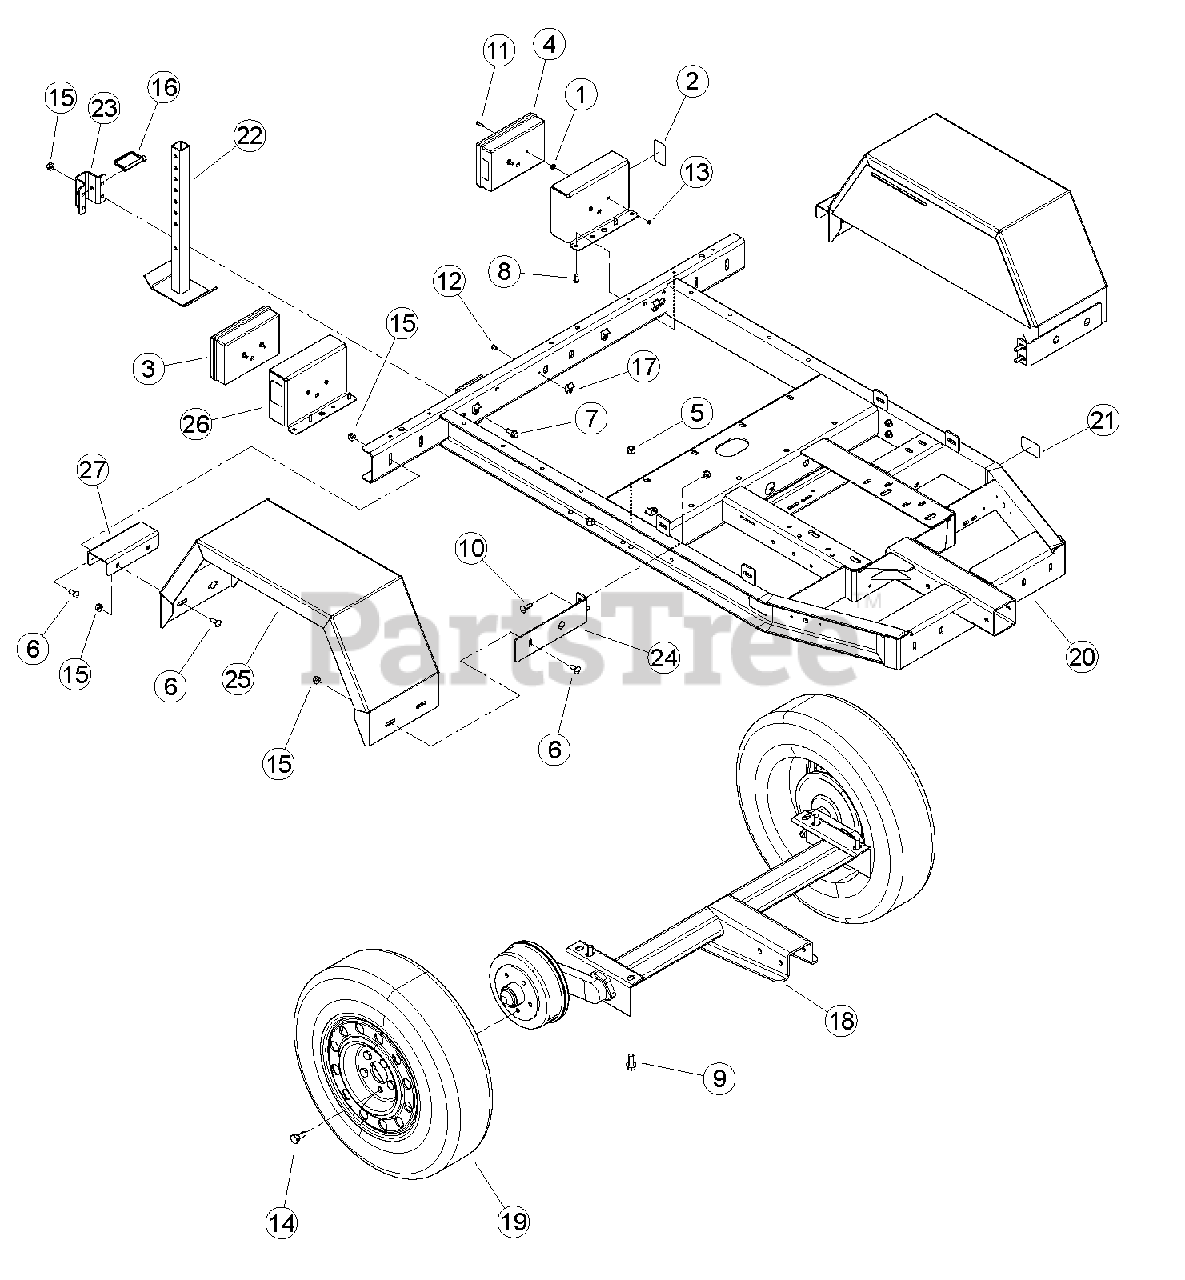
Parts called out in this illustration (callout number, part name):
1	GROMMET, 1/4 X 5/8 RUBBER
2	REFLECTOR, WIDE ANGLE RED
3	LIGHT, TAIL RH
4	LIGHT, TAIL LH
5	NUT, 1/2" CENTERLOCK GRB ZP
6	BOLT, 3/8 X 1" GR5 CRG NC ZP
7	BOLT, 3/8 X 1 FLANGE NC
8	SCREW, 11/32 X 7/8 HWH AB THREAD ZP
9	BOLT, 1/2 -13 X 1-1/4 FLANGE NC
10	BOLT, 3/8 X 1-1/4" GR5 CRG NC ZP
11	BOLT, 10-24 X 3/4" HHCS GR8 PLAIN
12	RIVET, AL BLIND 1/4 X 3/4 DOME HEAD
13	NUT, #10-24 K-LOCK ZP
14	BOLT, 12MM LUG FOR WHEELS
15	NUT, 3/8-16 NYLOCK FLANGE
16	PIN, 3/8 X 2-3/4" SNAP
17	CLAMP, CABLE MOUNT
18	AXLE, TORSION W/ BRAKES
19	WHEEL/TIRE, P205/65R15
20	ASSEMBLY, CH611DHXE/XF TRAILER W/ DECALS VI
21	REFLECTOR, WIDE ANGLE AMBER
22	WELDMENT, REAR STABILIZER
23	GUIDE, TRAILER SUPPORT
24	BRACKET, FENDER
25	WELDMENT, CHIPPER FENDER
26	BRACKET, TAIL LIGHT
27	PLATE, FENDER SPACER
